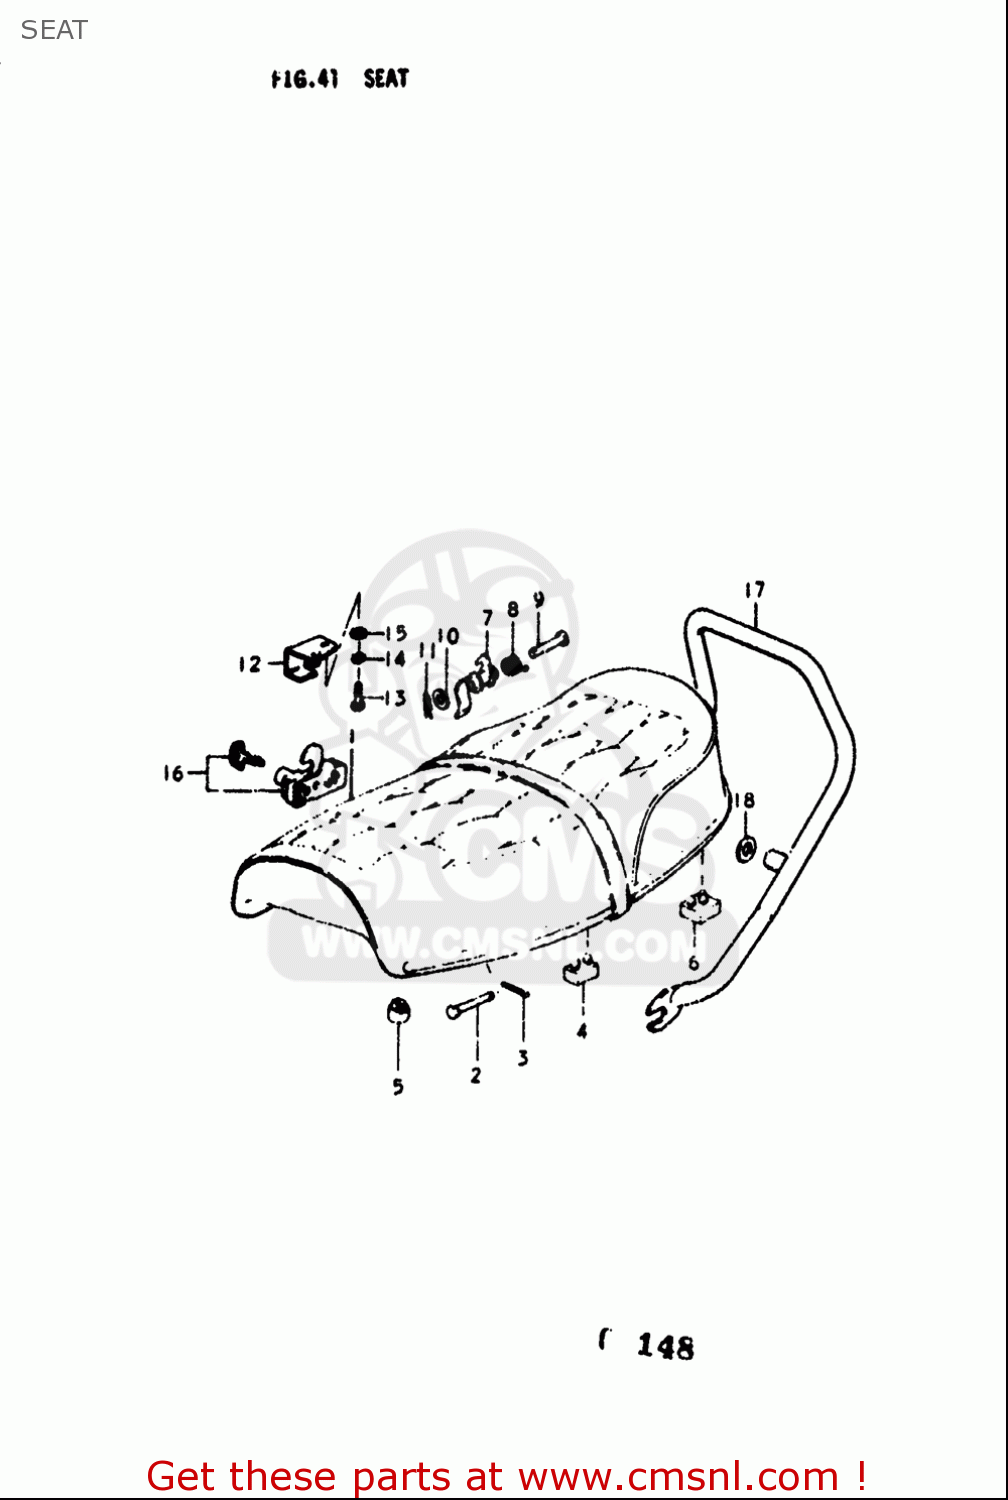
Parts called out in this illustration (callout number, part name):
1	SEAT ASSY
2	PIN
3	PIN
4	CUSHION
5	CUSHION(11.5X22X20)
8	SPRING
9	PIN
10	WASHER
12	PLATE,SEAT CLAMP GUIDE
13	BOLT
14	WASHER,LOCK
15	WASHER
16	LOCK SET,HELMET
18	WASHER (8.2X22X3.2)
